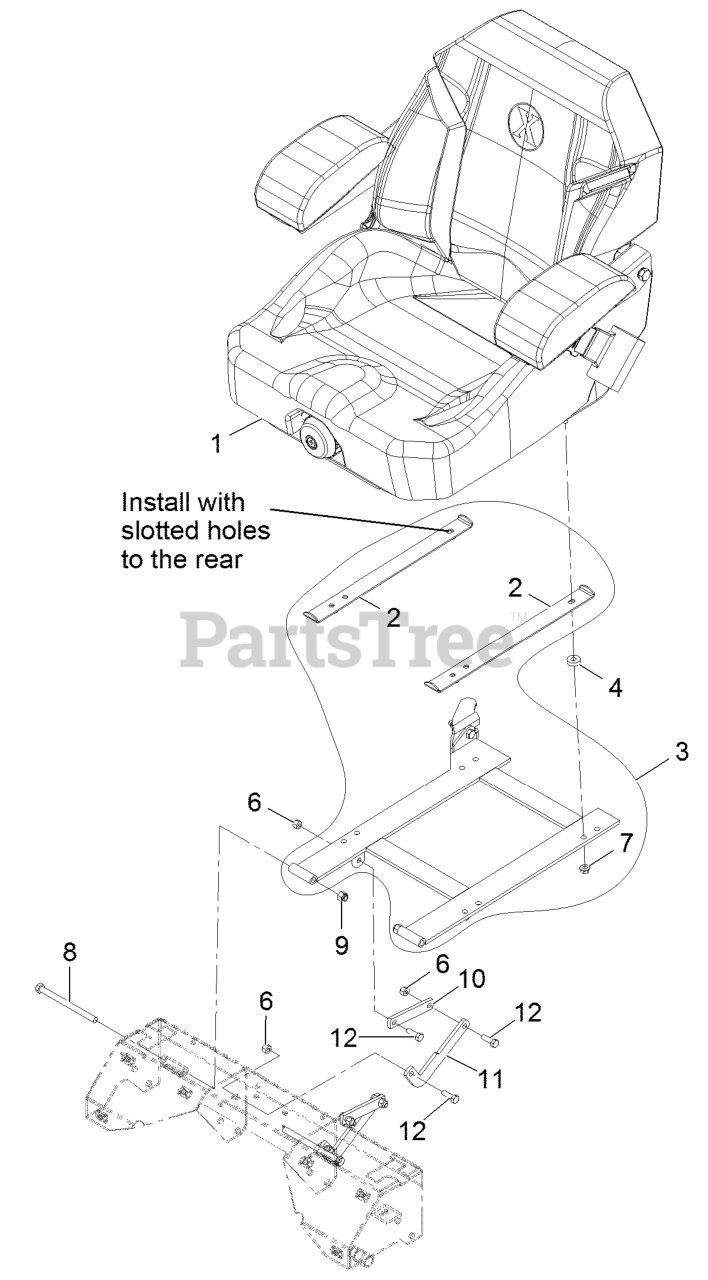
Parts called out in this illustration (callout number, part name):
1	KIT-SUSPENSION SEAT
2	STOP/SPACER-SEAT
3	KIT,SEAT FRAME SERVICE
6	NUT-LOCK, NI
8	SCREW-HH
9	NUT-LOCK, NI
10	LINK-STOP, SEAT
11	LINK-STOP, SEAT
12	SCREW-HH
